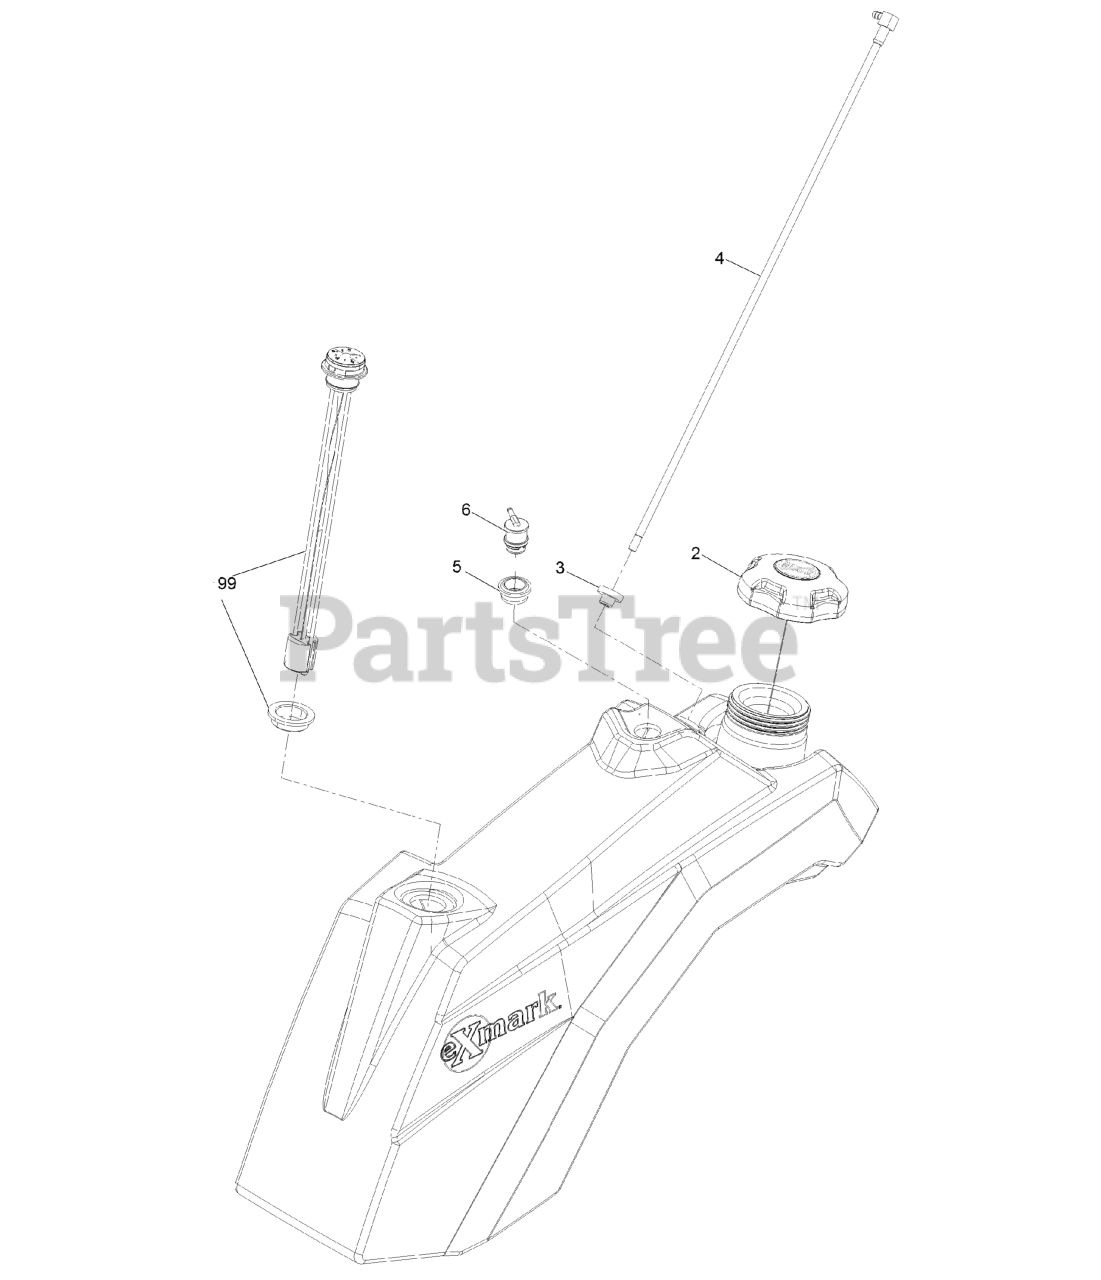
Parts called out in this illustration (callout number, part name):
2	CAP-FUEL, RATCHETING
3	BUSHING
4	STRAW, FUEL, LONG
5	GROMMET
6	VALVE-VENT, FUEL
99	KIT-FUEL GAUGE REPLACEMENT
